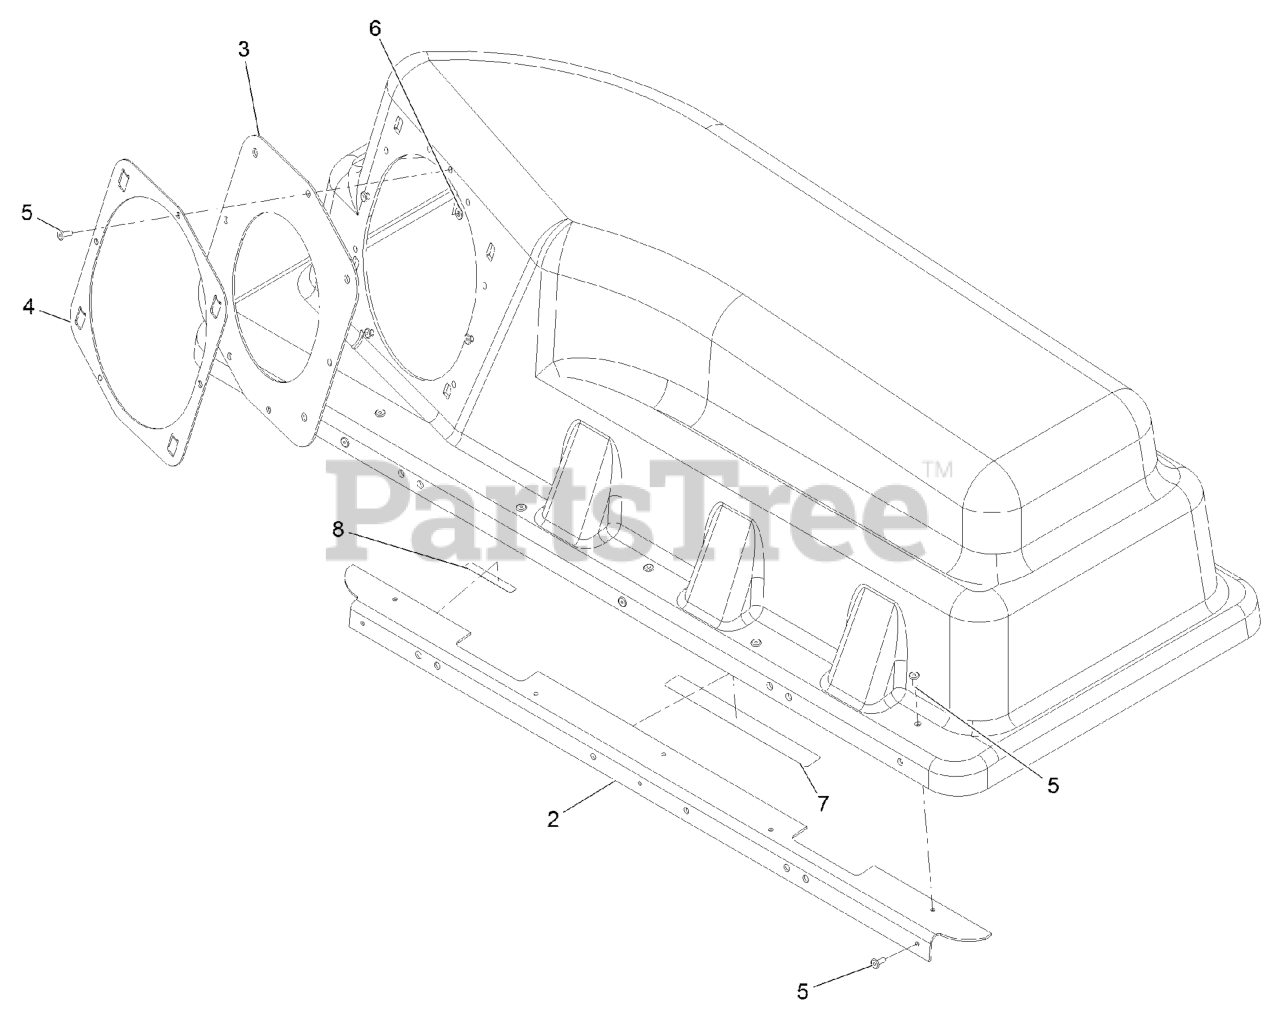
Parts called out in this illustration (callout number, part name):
2	STIFFENER-BAGGER TOP
4	RING-RETAINER
5	RIVET-BLIND
6	WASHER-FLAT
7	DECAL-CAUTION, BAGGER
